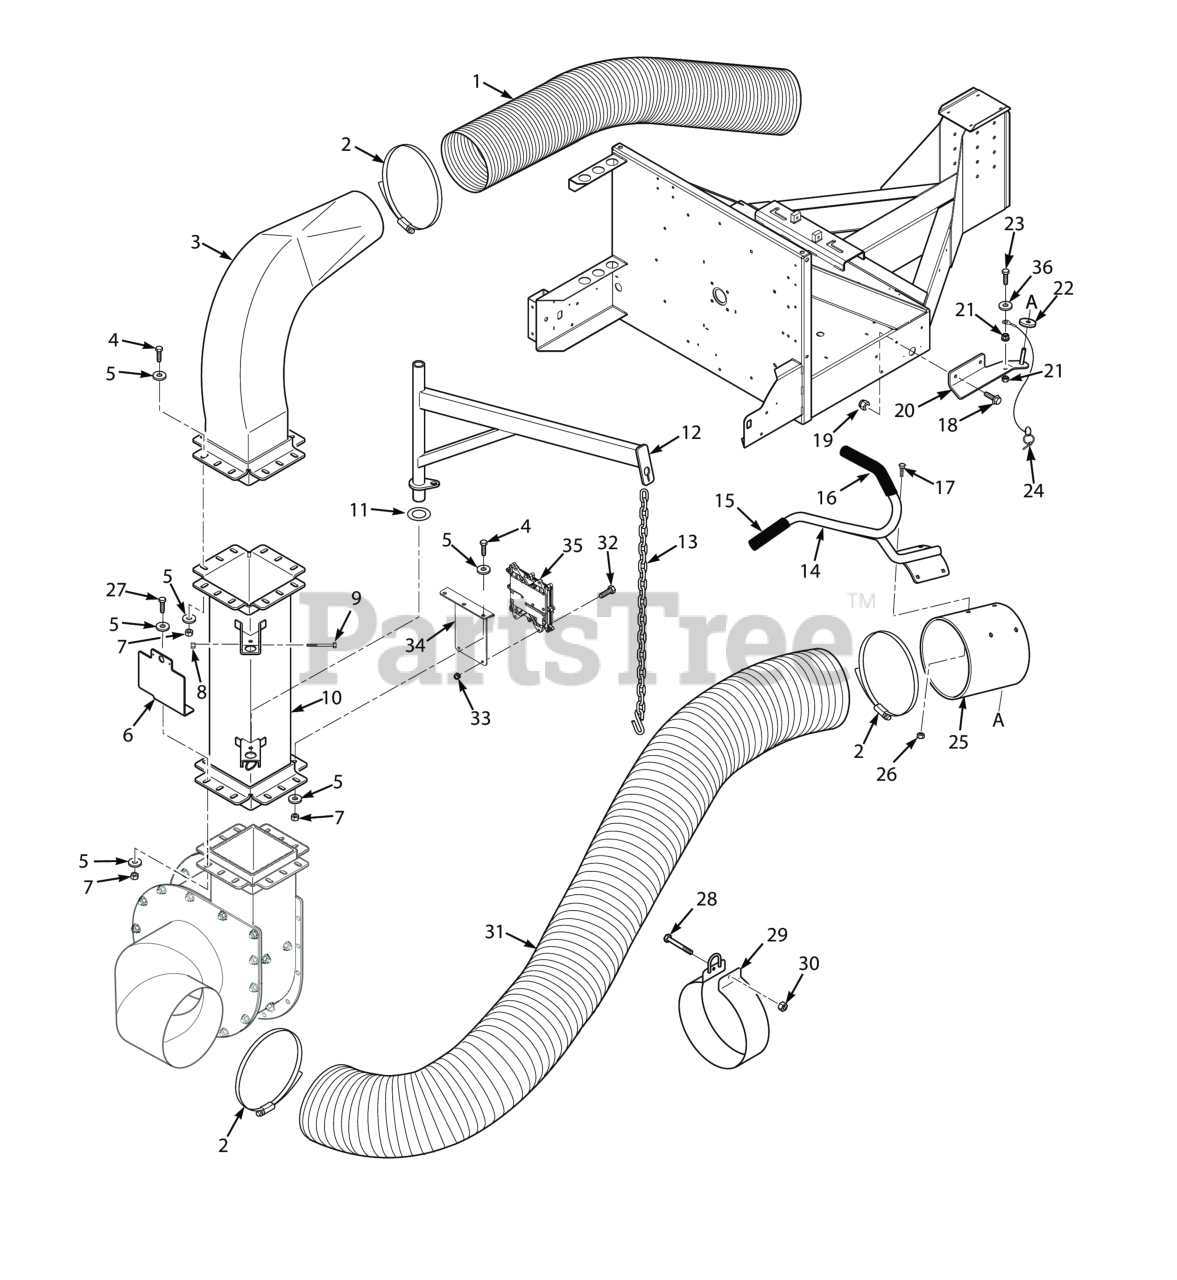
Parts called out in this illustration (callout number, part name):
1	Hose, Clear Poly 12" x 84"
2	Strap, Ratchet- 66 x 1"
3	Elbow, Exhaust - TLB25
4	Bolt, Hex Head 1/2-13 x 1-1/2", (STT-52 & STTII-52)
5	Flat Washer, 1/2 (.562 x 1.375 x .109)
6	License Plate Holder Assembly (INCL Bracket and Light Assembly)
7	HEX LOCKNUT, ELASTIC STOP, 1/2-13
8	HEX, NUT, ELASTIC STOP LOCK, 1/4-20
9	Bolt, Hex Head 1/4-20 x 4"
10	Stack Assembly, w/Decals (INCL. 8,9,11,12)
11	Disk, Anti-Friction
12	Boom Weldment
13	Chain w/2-Hooks
14	Handle w/Grips
15	Grip, Handle 1-1/4" x 6"
16	Grip, Handle 1-1/4" x 20"
17	Carriage Bolt, 3/8-16 x 1.0"
18	Bolt, Hex Head Serrated Flange 3/8-16 x 3/4"
19	NUT, 3/8-16 SERRATED FLANGE HEX HEAD
20	Hose Holder Weldment
21	Nut, Serrated Flange 5/16-18 (Right Front Engine Mounting, Briggs and Kohler Only)
22	Washer, Rubber
23	Bolt, Hex Head 5/16-18 x 1-1/2" (Right Front Engine Mounting, Briggs and Kohler Only)
24	Quick Pin Assembly w/Lanyard
25	Nozzle w/Decal
26	HEX NUT, ELASTIC STOP LOCK, 3/8-16
27	Bolt, Hex Head 1/2-13 x 1-3/4"
28	Bolt, Hex Head 5/16-18 x 3.00"
29	Band, Hose Support - 16"
30	HEX NUT, ELASTIC STOP LOCK, 5/16-18
31	Hose, 16" x 84" - .045 P.U. w/Wire
32	Bolt, Heax Head 5/16-18 x 1" (48V / 52V)
33	Nut, Flange Head Elastic Stop 5/16-18
34	Mounting Bracket, ECU
35	ECU, TLB25-49KBD
36	Flatwasher, 5/16-.344 x .688 x .065 (48V / 52V)
